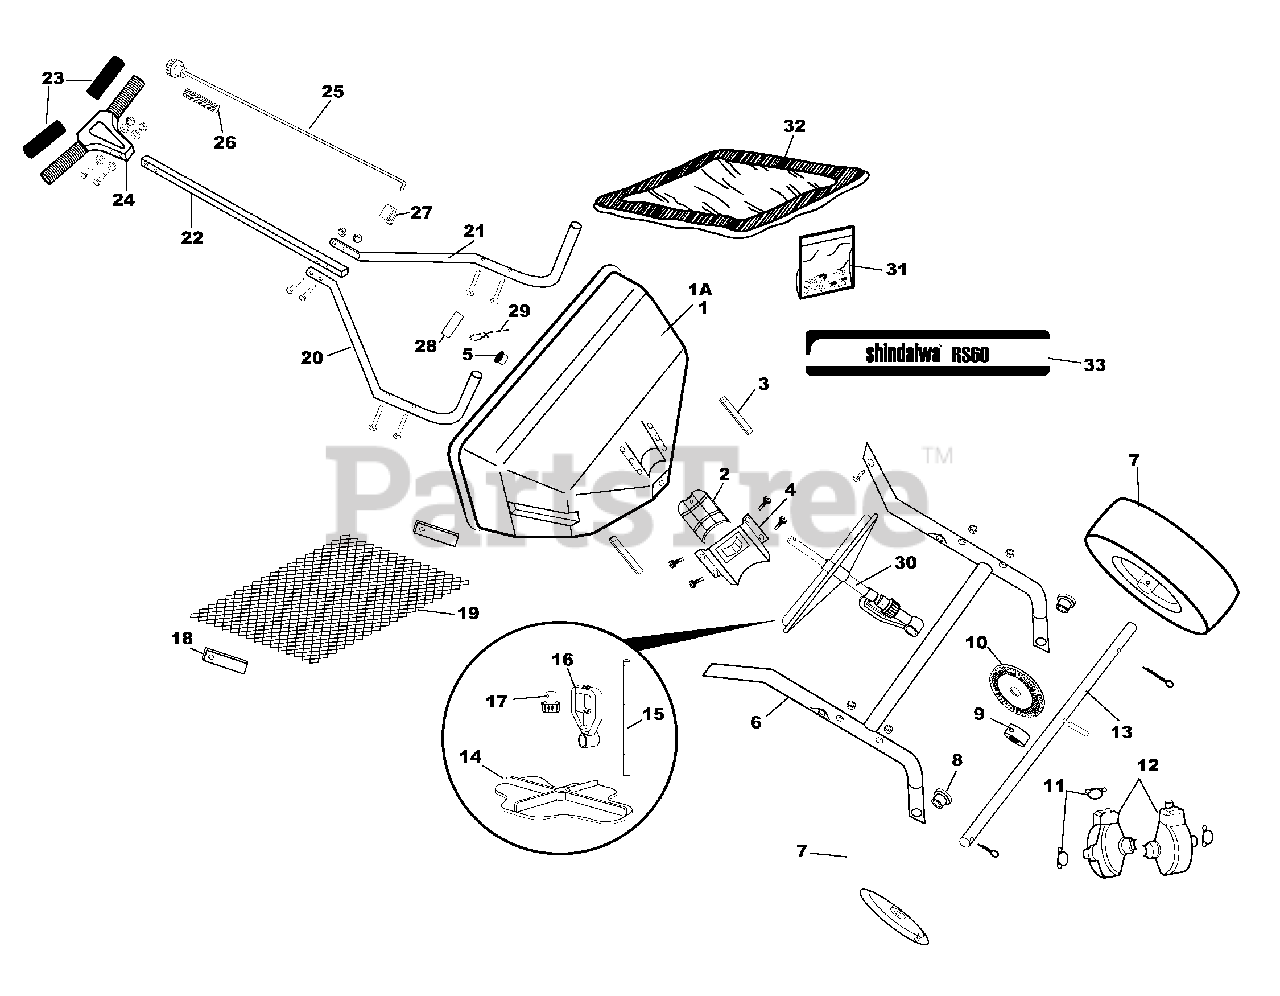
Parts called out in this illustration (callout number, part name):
1	Hopper Assembly
1A	Hopper
2	Shutoff Plate
3	Shutoff Plate Guides
4	Rate Cam & Chute Assembly
5	Impeller Shaft Bearing
6	Frame Assembly
7	Drive & Free Turning Wheel
8	Axle Bushings
9	Axle Collar
10	Axle Gear
11	Gear Cover Clamps
12	Gear Cover
14	Impeller
15	Impeller Shaft
16	Gear Support
17	Pinion Gear
18	Screen Clips
19	Hopper Screen
20	Handle Brace W/ Plug– LH.
21	Handle Brace W/ Plug– RH.
22	Handle Tube
23	Handle Grips
24	T-Handle Assembly
25	Control Knob & Wire Ass’y.
26	Control Knob Spring
27	Wire Retaining Clip
28	Hopper Plug
29	Agitator
30	Impeller Assembly
31	Parts Package
32	Hopper Cover
33	Hopper Label
